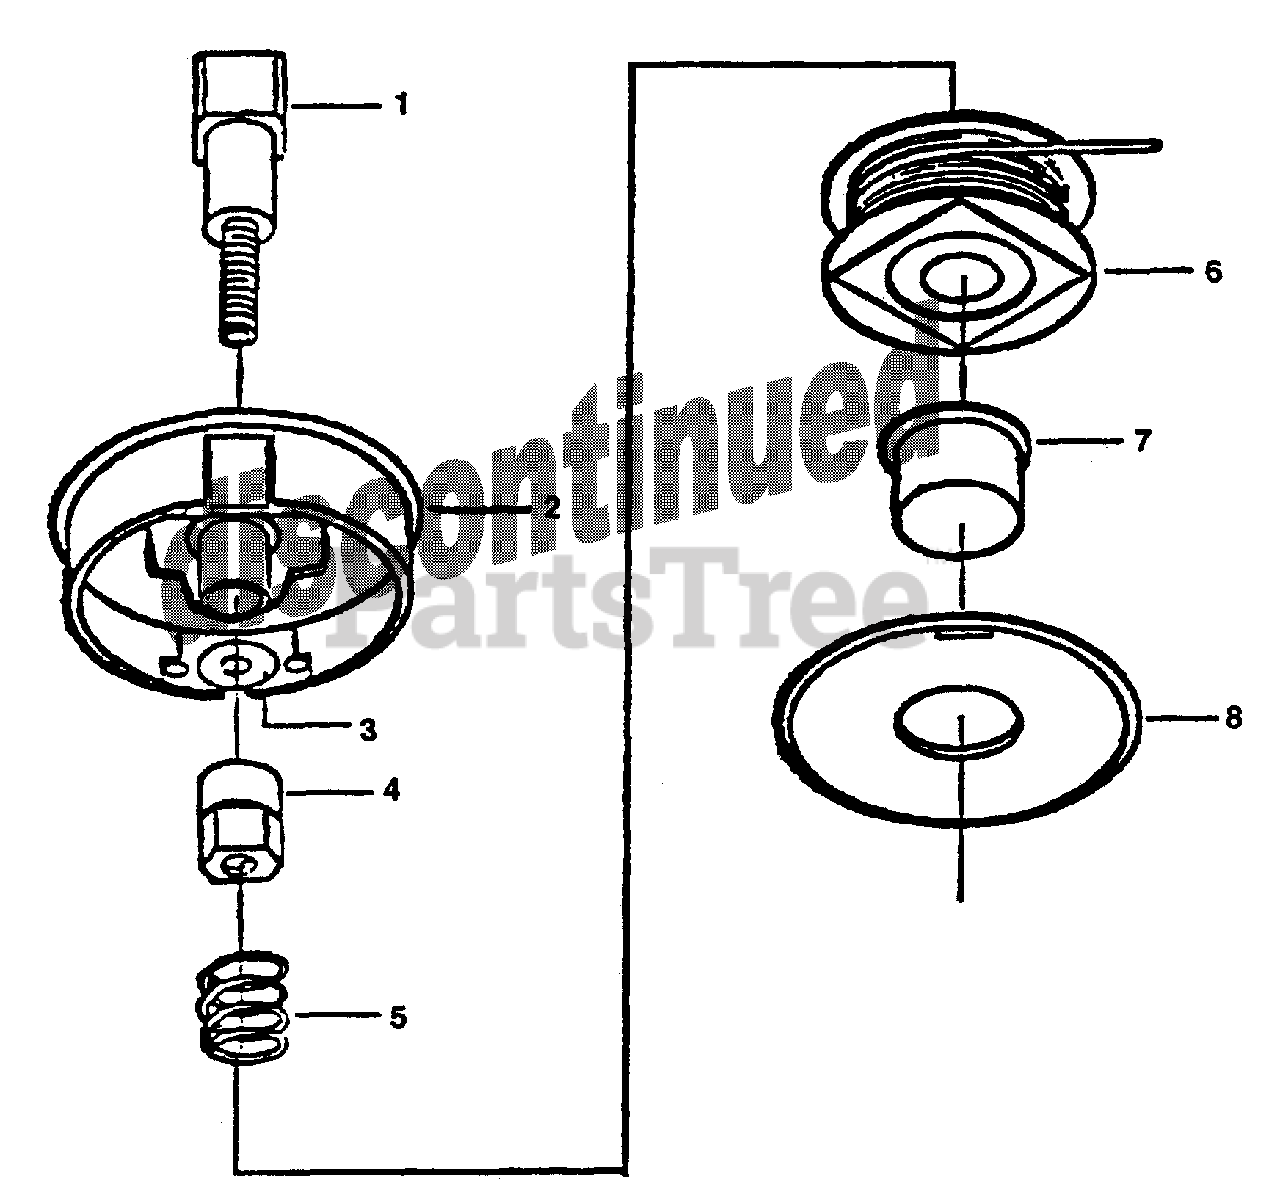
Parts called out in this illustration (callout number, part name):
1	BOLT - 3/8-24
2	HOUSING
3	EYELET
5	SPRING
6	SPOOL
7	BUTTON
8	COVER
